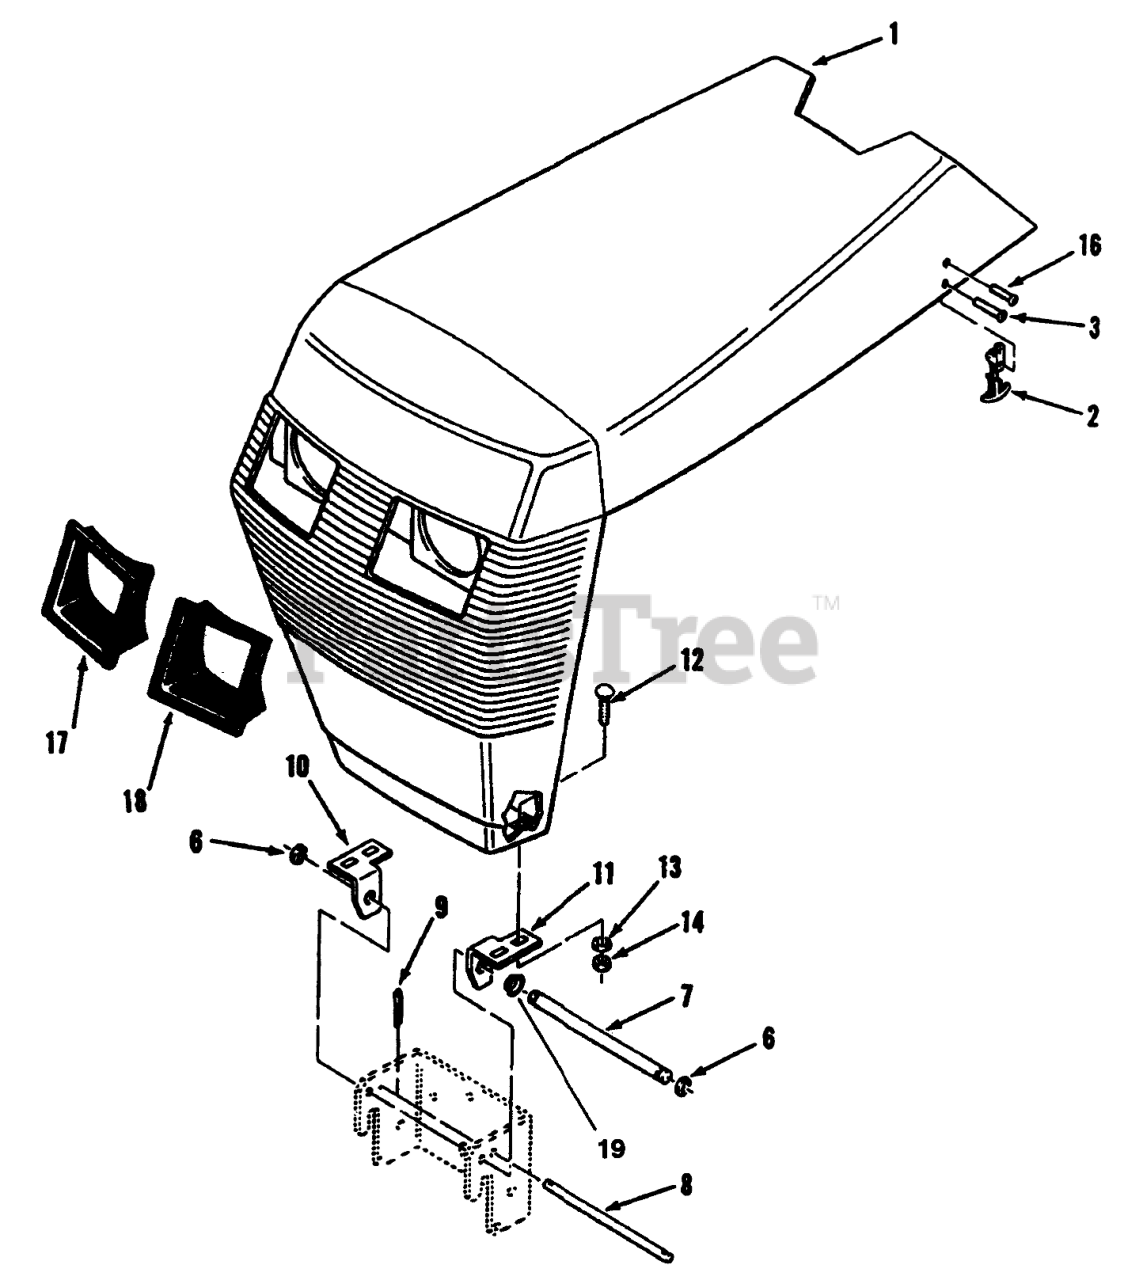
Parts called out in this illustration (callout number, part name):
1	SERV.ASSY-HOOD & PKG
2	LATCH-FLEX BLK ASS'Y
3	RIVET-POP
6	RING-RETAINING
7	ROD-GRILL PIVOT
8	ROD-HOOD STOP
9	Cotter Pin
10	BRACKET-GRILL, R H
11	BRACKET-GRILL, LH
12	SCREW-CARR
13	WASHER-FLAT
14	NUT-HEX
16	NUT-LOCK, NI
17	BEZEL-HEADLIGHT, RH
18	BEZEL-HEADLIGHT, LH
19	NYLINER BUSHING
